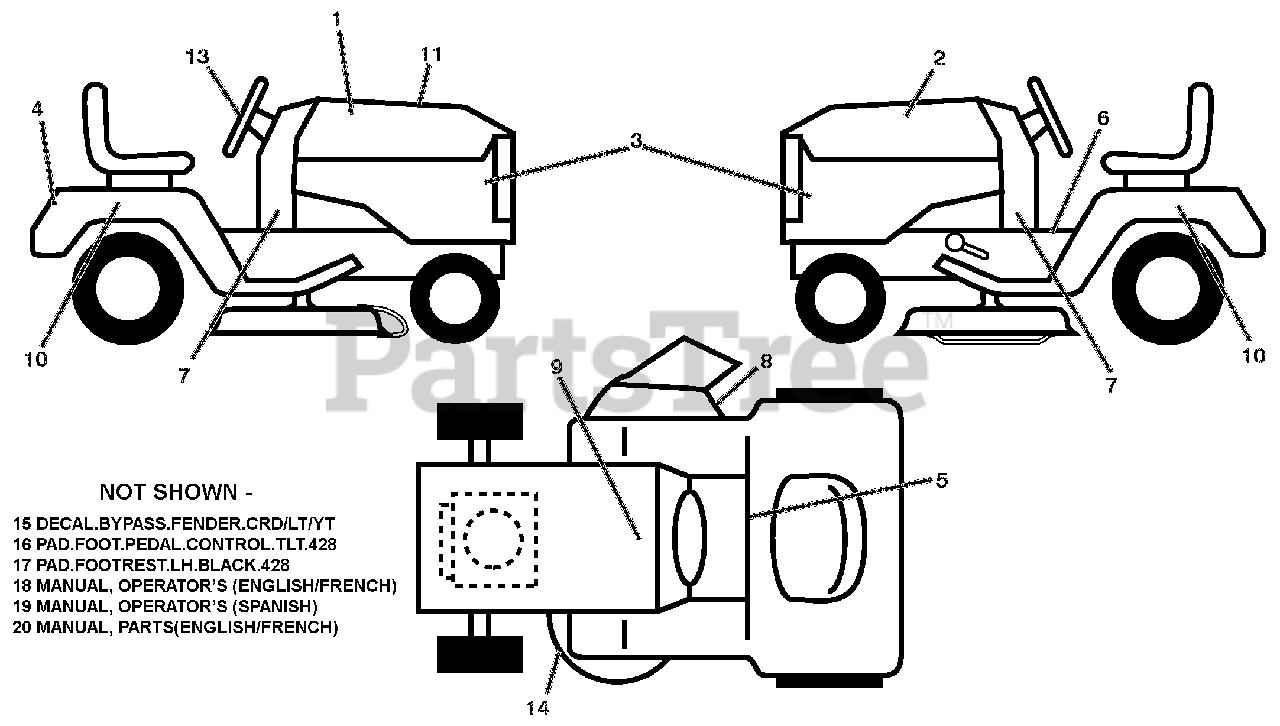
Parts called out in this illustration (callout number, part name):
1	DECAL.HOOD.RH.3HIGH.ARIENS
2	DECAL.HOOD.LH.3HIGH.ARIENS
3	DECAL.SDPNL.PWRDBY KOHL.ARIENS
4	Decal, Fender
5	Decal, Flag
6	DECAL.FENDER.WARNING.ENG/FR.07
7	DECAL.DASH.LOWER.
8	DECAL.MOWER.WARN.KEEP HAND AWY
9	DECAL.BAT.DAN/POI P/L SYM.WPN
10	DECAL.FENDER.SIDE.HYDRO.ARIENS
11	PARTS MANUAL
13	DECAL.WHEEL.STEER.ARIENS
14	DECAL.V-BELT.SCH.42/46"MEC/ELE
